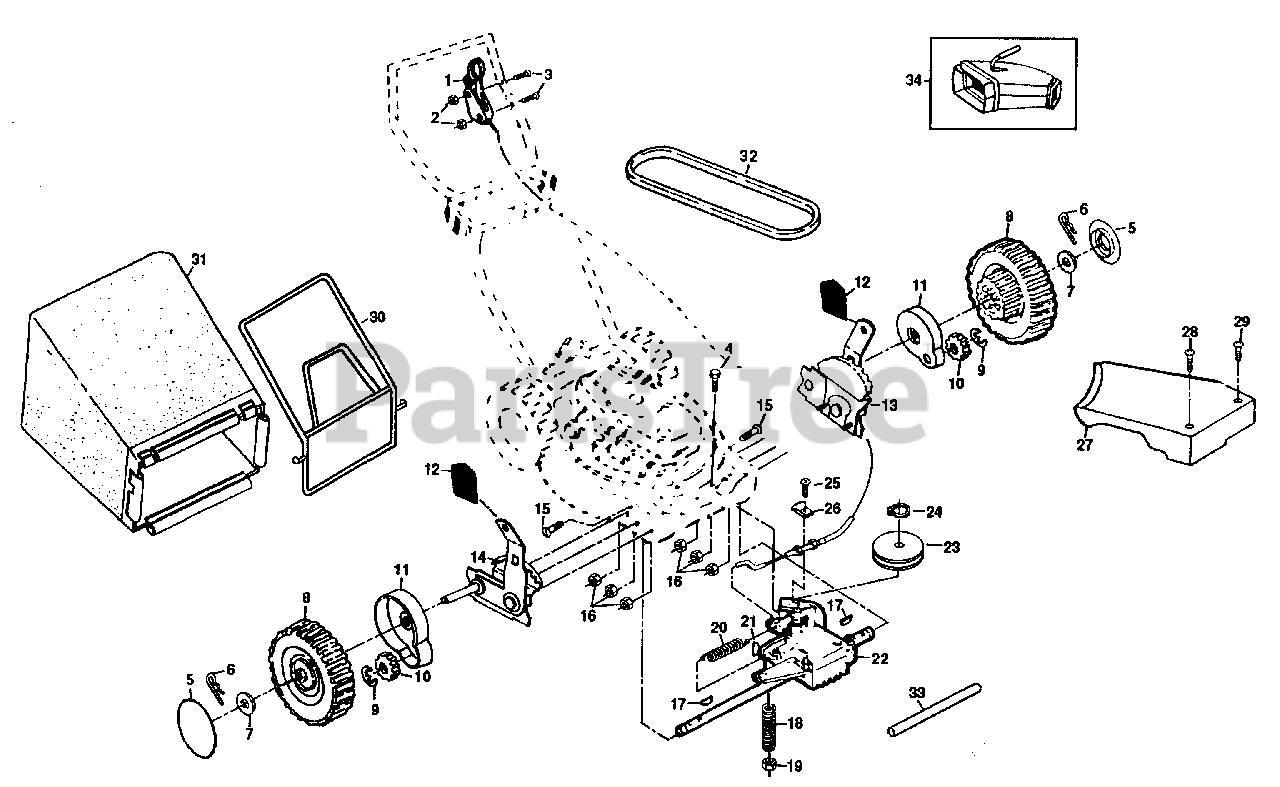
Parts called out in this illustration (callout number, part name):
1	Drive Control (AYP part number)
2	Locknut #10-24 (AYP part number)
3	Pan Head Machine Screw #10-24 x 2 (AYP part number)
4	Hex Head Bolt 1/4-20 x 2-3/4 (AYP part number)
6	Retainer Clip (AYP part number)
7	Washer (AYP part number)
8	Wheel & Tire Assembly 8.00 x 1.75 (AYP part number)
9	E-ring (AYP part number)
10	Pinion (AYP part number)
11	Dust Cover (AYP part number)
12	Selector Knob (AYP part number)
13	Wheel Adjuster Assembly (Left) (AYP part number)
14	Wheel Adjuster Assembly (Right) (AYP part number)
15	Flat Head Machine Screw 1/4-20 x 3/4 (AYP part number)
16	Locknut (AYP part number)
17	Woodruff Key #3 (AYP part number)
18	Spring (AYP part number)
19	Locknut 1/4-20 (AYP part number)
21	Woodruff Key #213 (AYP part number)
22	Gear Case Assembly (AYP part number)
23	Drive Pulley (AYP part number)
24	Retaining Ring (AYP part number)
25	Pan Head Self-Tapping Screw #10-24 (AYP part number)
26	Cable Clamp (AYP part number)
27	Drive Cover (AYP part number)
28	Pan Head Machine Screw #10-24 x 2-3/4 (AYP part number)
29	Pan Head Machine Screw #10-24 x 1-3/4 (AYP part number)
30	Catcher Frame (AYP part number)
31	Grass Catcher
33	Drive Shaft Cover (AYP part number)
